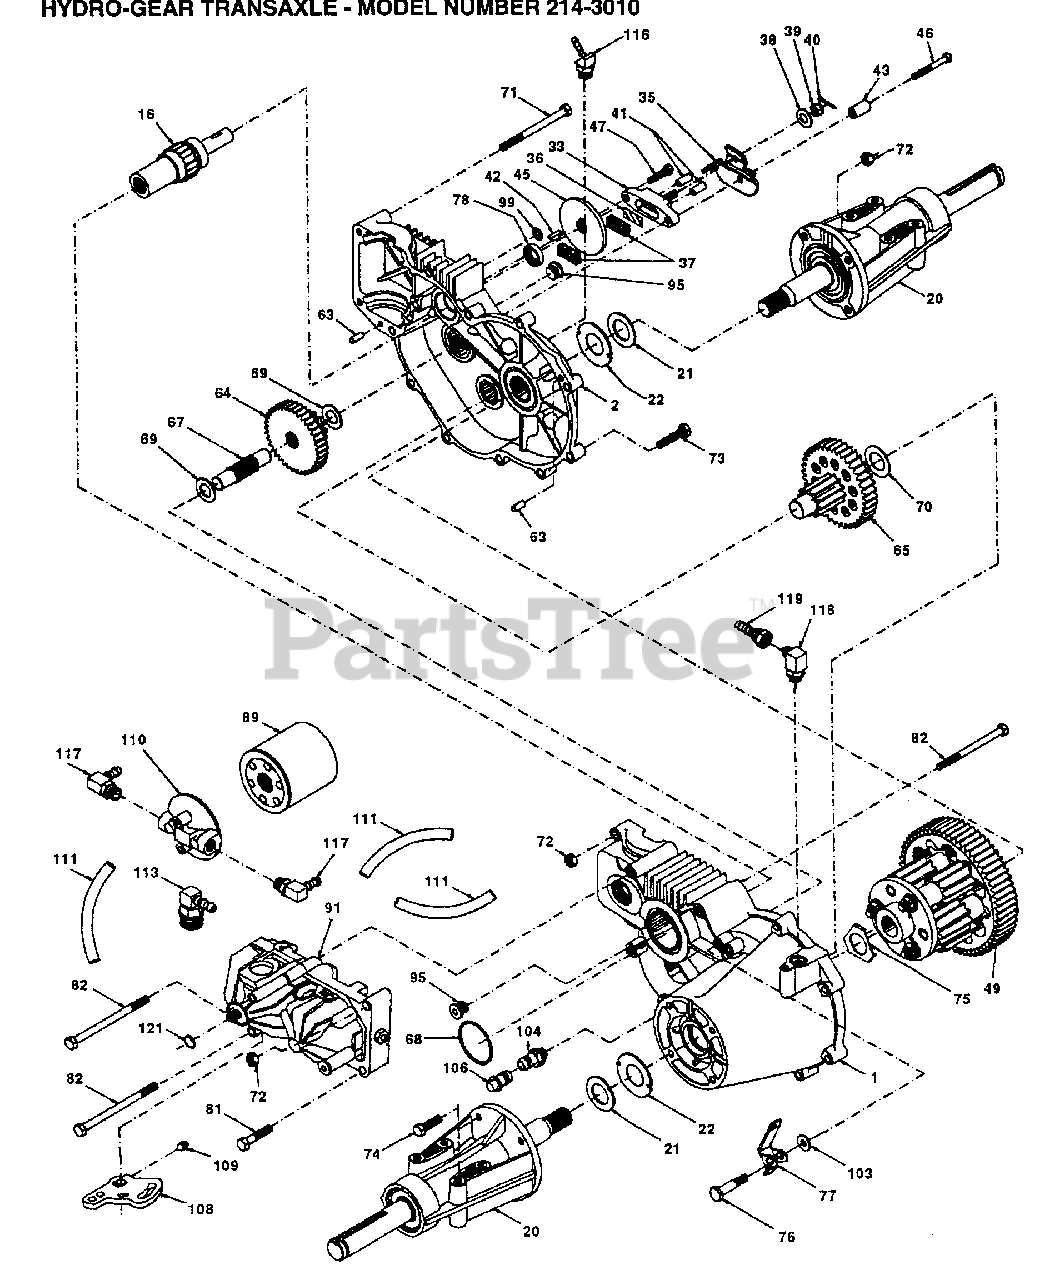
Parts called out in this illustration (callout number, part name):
1	HOUSING LH 70086
2	HOUSING RH 70088
16	SHAFT BRAKE 62877
20	AXLE MTG 70087
21	WASHER 44805
22	WASHER 44806
33	YOKE.BRAKE.62589
35	ARM BRAKE 50214
36	PUCK PLATE 44134
37	PUCK BRAKE 44132
38	WASHER HYD 44130
41	PIN BRAKE 44127
42	KEY HI PRO 44143
43	SPACER 50259
45	DISC BRAKE 44090
46	BOLT 1/4-20 44276
47	BOLT 1/4-20 44433
49	DIFFERENTIAL62834
63	PIN DOWL 44757
64	GEAR R14-38 44775
65	PINION DRIV 70051
67	SHAFT-44779
68	O RING 44781
69	WASHER 44795
70	WASHER 44794
71	BOLT 5/16 44827
72	NUT HXLK 43064
73	BOLT 5/16 44841
74	SCREW 5/16 45089
75	WASHER DIF 44880
76	BOLT SHOULD 44785
77	ARM FREEWHL 44786
78	SEAL.OIL.44761
81	BOLT 5/16 43084
82	BOLT 5/16 44820
89	FILTER SPIN 50037
95	PLUG.9005110-5600
103	WASHER.50169
104	CAP.VENT.70109
106	O-RING.ASM.70110
108	ARM.CONTROL.45007
109	SCREW.SET.50018.
110	FILTER.HEAD.50207
111	HOSE.5/16.50208.
113	FITTING.SAE.50210
116	FITTING.SAE.50213
117	FITTING.SAE.50249
118	FITTING.MAL.50251
119	FITTING.FEM.50250
121	RING.RET.2003016.
